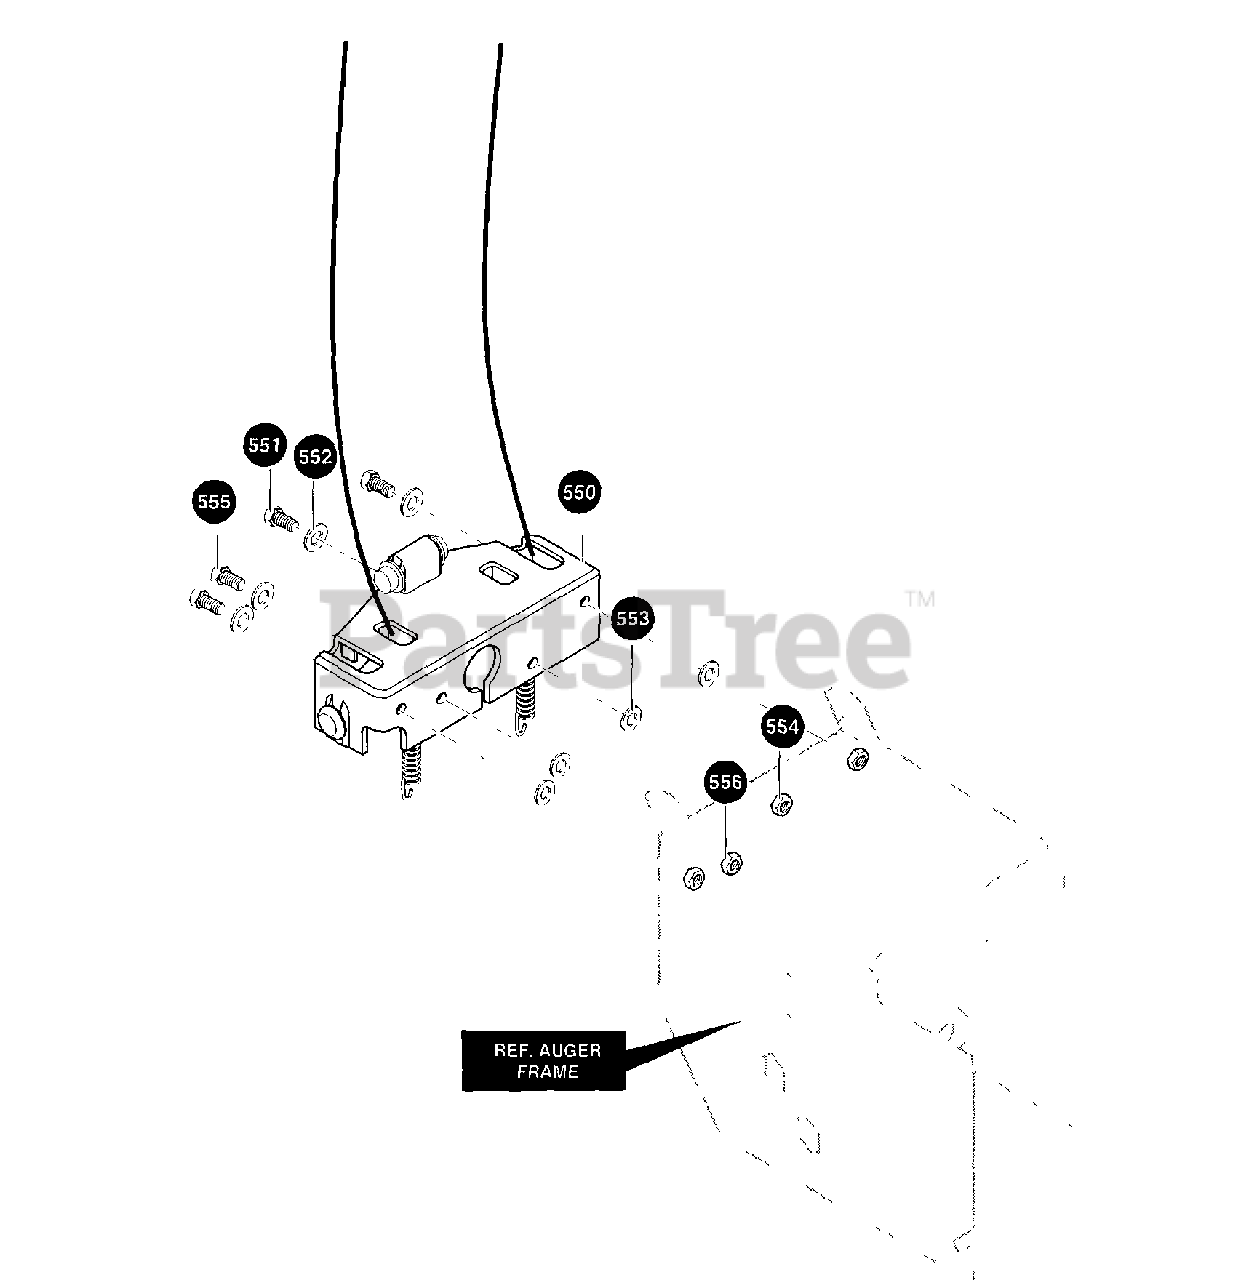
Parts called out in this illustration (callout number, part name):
550	CONTROL, ASSY SINGLE HAND
551	SCREW, 5/16-18 X .75 HHC
552	WASHER, FLAT .344 X .69 X 065
553	WASHER, HVSPTLK .328 X .60 X.09
554	NUT, 5/16-18 REGHEX
555	SCREW, 5/16-24 X 1.00 HHC
556	NUT, 5/16-24 HEXWDFLLK
